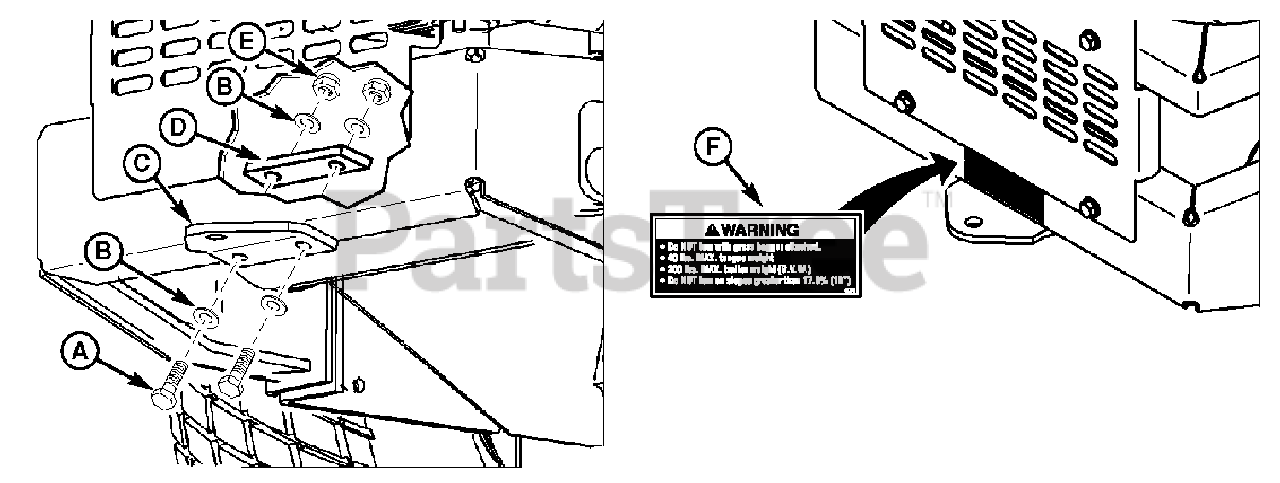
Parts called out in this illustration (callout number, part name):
A	BOLT, 3/8-16 x 1-1/2"
B	WASHER, 3/8 SAE
C	PLATE, Trailer Hitch
D	PLATE, Support
E	NUT, 3/8-16 HEX NYLON LOCK
F	DECAL, Trailer Warning
